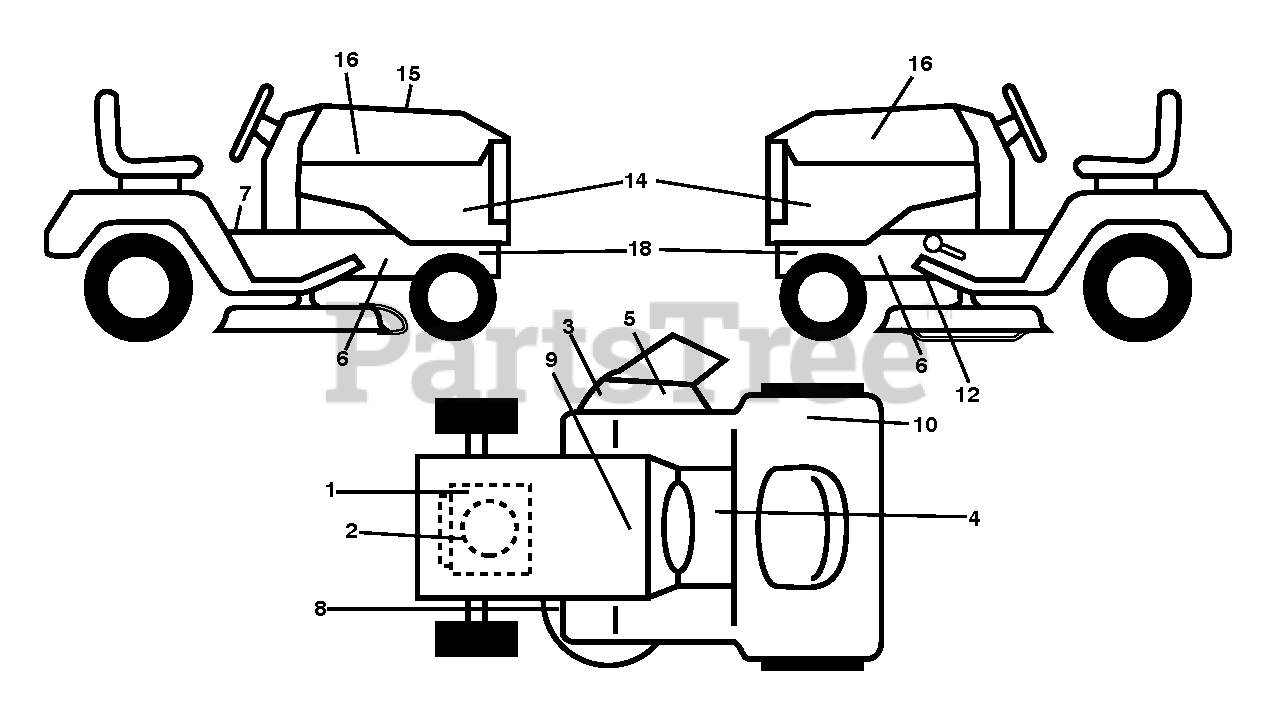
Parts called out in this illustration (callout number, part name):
1	DECAL.ENGINE.WARNING
2	DECAL.ENG.BS.724.ENDUR.382293
3	DECAL.DECK.6MIL.EURO.NOSTEP
4	DECAL.FWD/REV.PEDAL.SYMBOL
5	DECAL.TRACT/ZTR.DECKWARN.HUSQ
6	DECAL.WARNING.SERVCE/FIRE
7	DECAL.TRAC.FNDR.GLBLWRNG.RDYST
8	DECAL.V-BELT.SCH.42/46"MEC/ELE
9	DECAL BTRY SYMBOLS
10	DECAL.DECIBAL.100DB
12	DECAL.PEDAL.HUSQ.CROWN
14	DECAL.SDPNL.HUSQGT.TS343.RH/LH
15	DECAL.RPL.BSM44.END.TLB.42F.K4
16	DECAL.BADGE.170MM.TEXTLOGO.
18	DECAL.CHASSIS.HOT.MUFFLER
